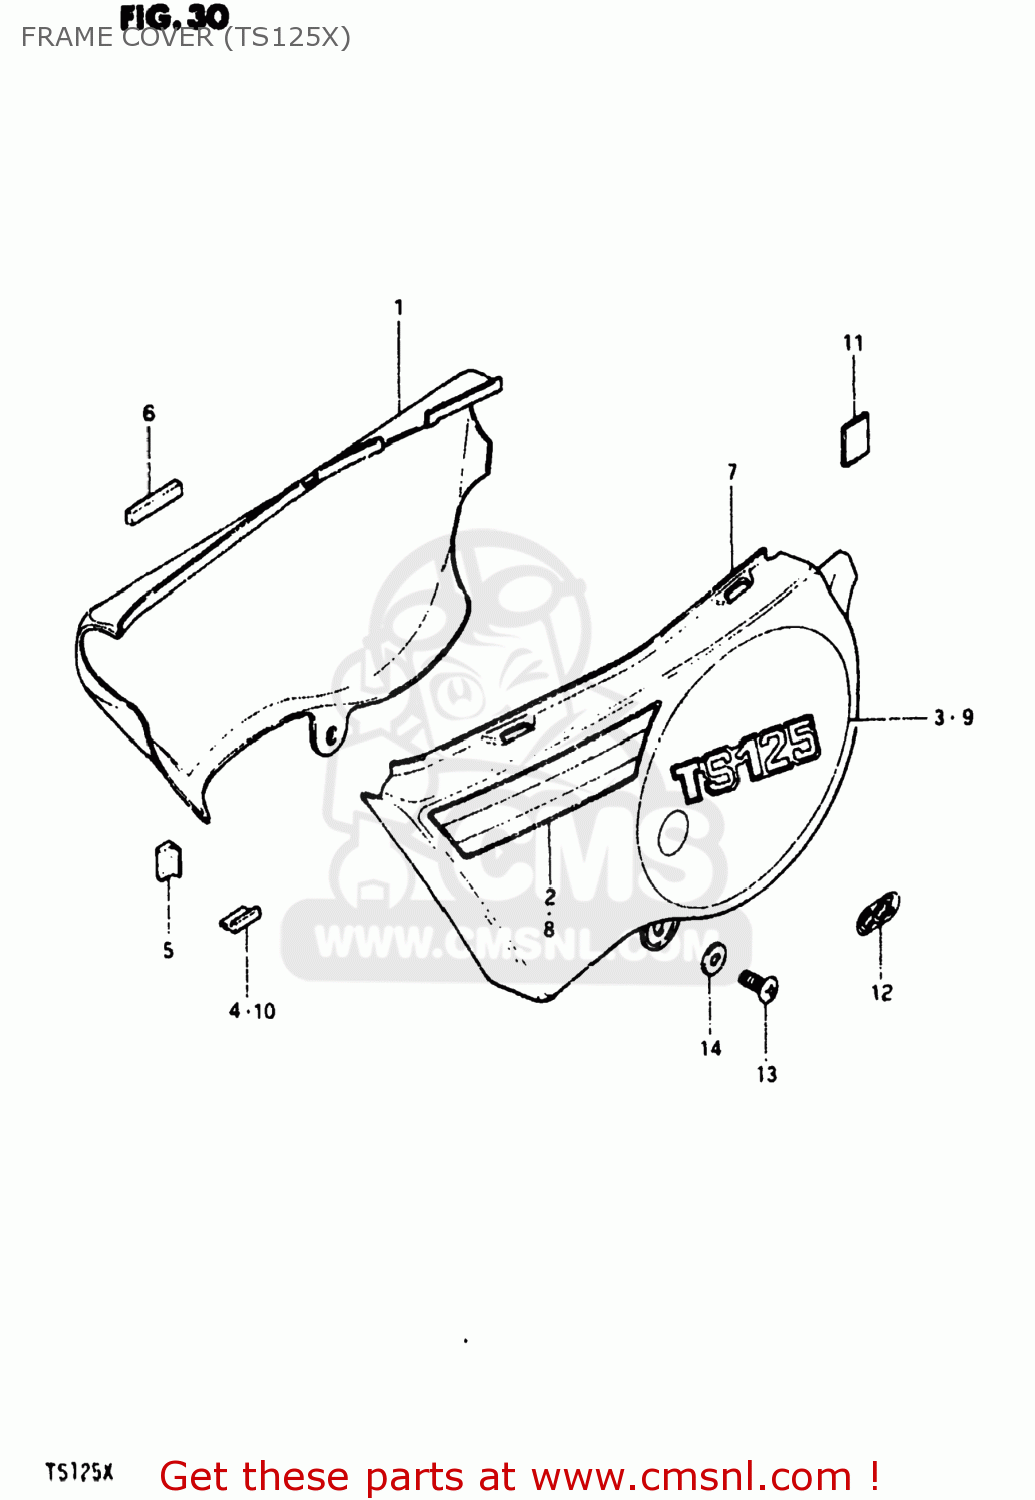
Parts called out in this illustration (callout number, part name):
1	COVER,FRAME,RIGHT
2	TAPE,FRAME COVER
3	EMBLEM,FRAME COVER,RIGHT
4	CUSHION,FRAME COVER
5	CUSHION,FRAME COVER
6	CUSHION,FRAME COVER
7	COVER,FRAME,LEFT
8	TAPE,FRAME COVER,LEFT
9	EMBLEM,FRAME COVER
10	CUSHION,FRAME COVER
11	PROTECTOR(170X95X3.0)
12	EMBLEM,CCIS
13	SCREW 6X12
14	WASHER
